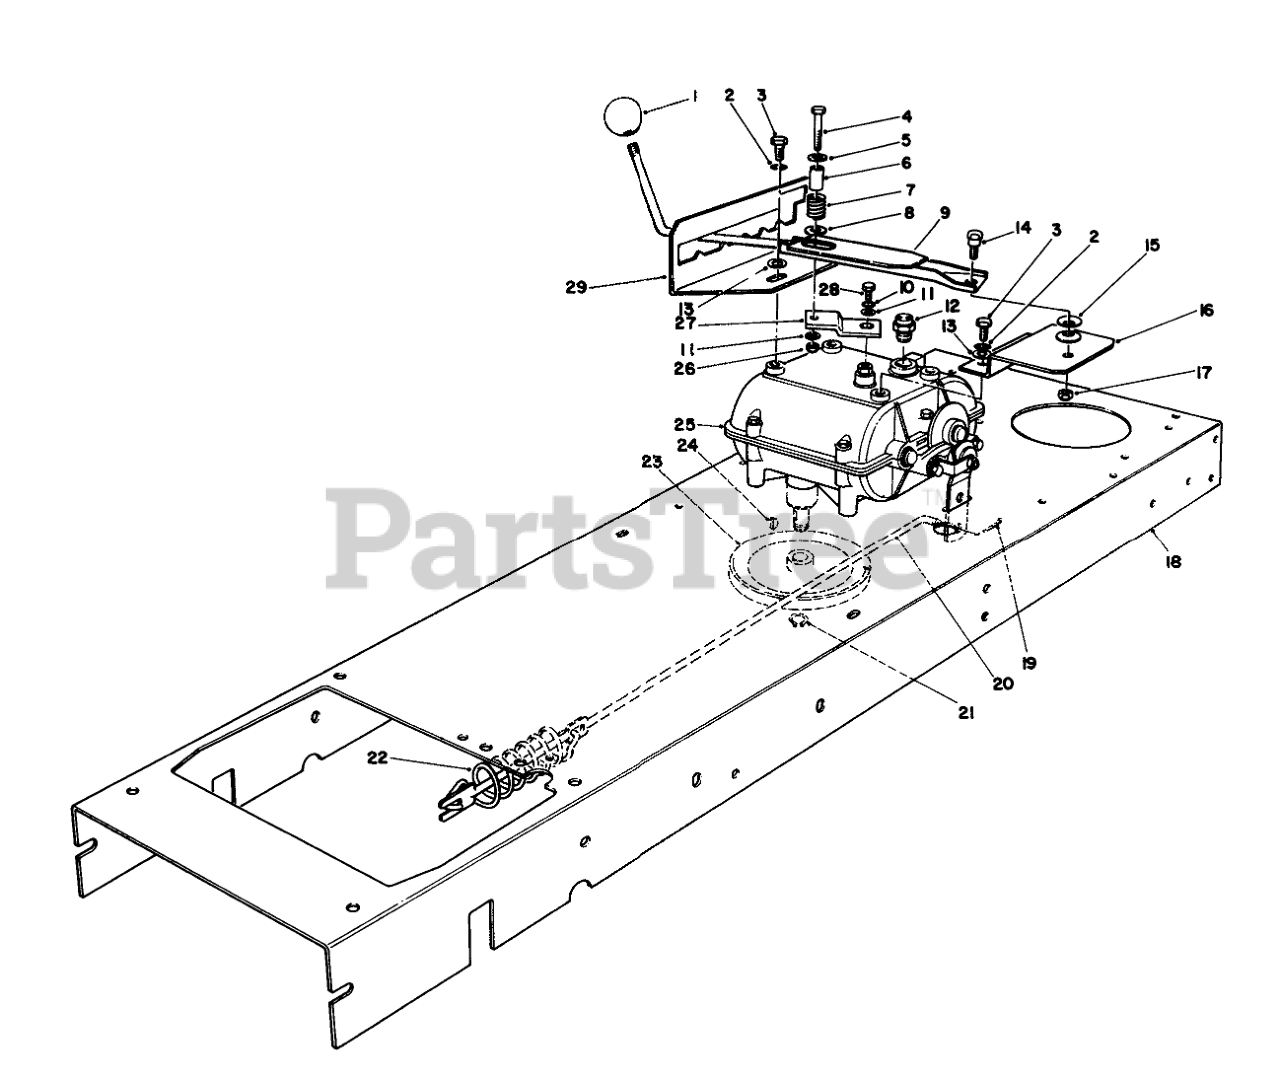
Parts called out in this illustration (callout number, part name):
2	Lockwasher
3	SCREW-HWHTF
4	SCREW-HH
5	WASHER-FLAT
6	SPACER-SPLIT
7	SPRING-COMPRESSION
8	Washer
9	SHIFT LEVER WA B
10	WASHER-LOCK
11	WASHER-FLAT
12	Switch-Neutral
13	WASHER-PLAIN
14	SCREW-SHOULDER
15	WASHER-BELLEVILLE
16	SHIFT MTG BRKT
17	NUT-LOCK, NI
18	Frame-Main
19	PIN-COTTER
20	BRAKE ROD
21	RING-SNAP, EXTERNAL
22	SPRING-EXT
23	PULLEY
24	KEY-WOODRUFF
25	TRANSMISSION
26	NUT-LOCK, CONE
27	LEVER-SHIFT
28	SCREW-HH
29	Gate-Shift
